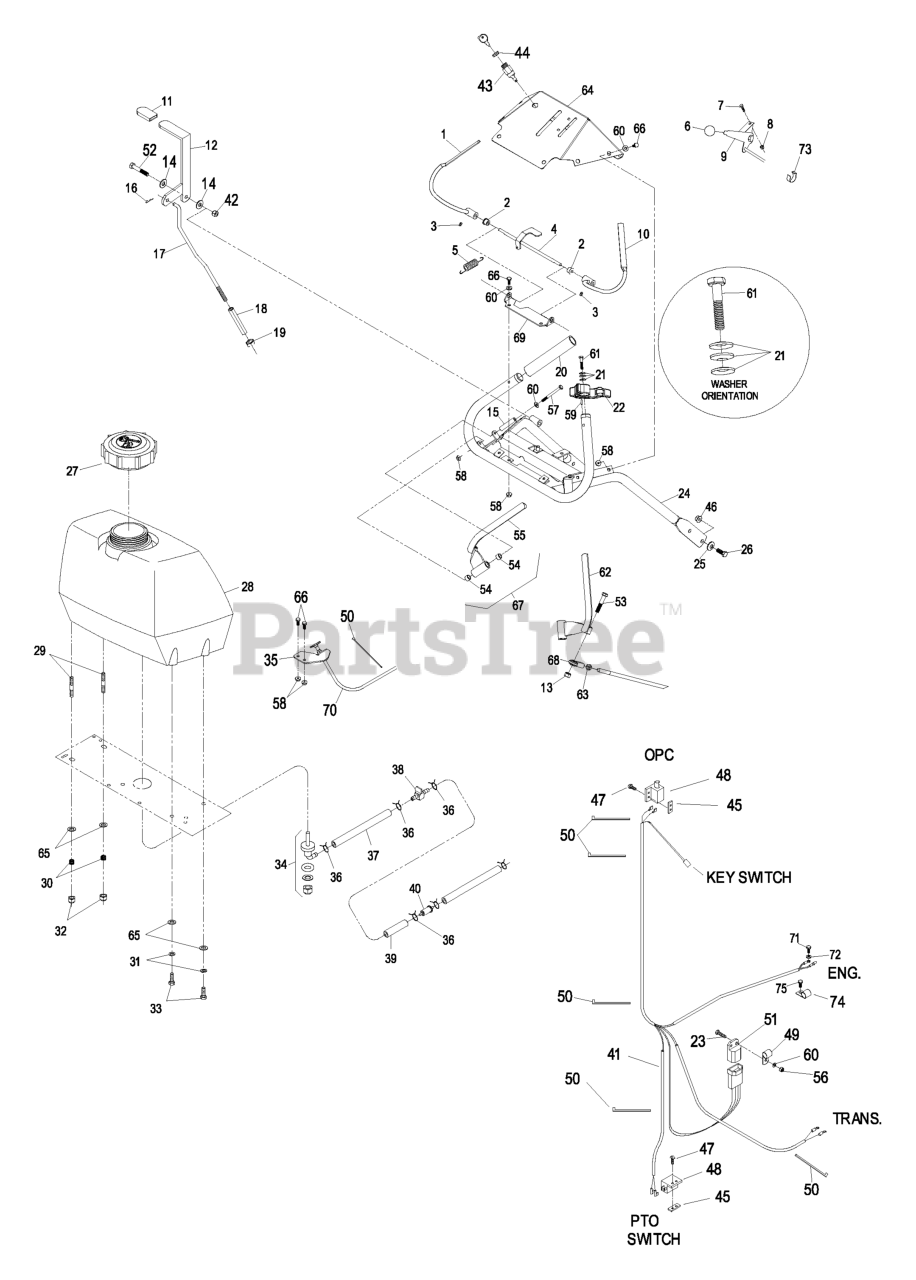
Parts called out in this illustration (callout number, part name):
2	BUSHING-NYLON
3	SCREW-SET
4	WLD,OPC LEVER AXLE
5	SPRING-EXTENSION
6	KNOB-BALL
7	BOLT-CARR
8	NUT-LOCK, NI
9	THROTTLE CABLE ASM
11	GRIP-LEVER
13	Nut, Nyloc 5/16-18
14	WASHER-FLAT
15	BUSHING-LEVER, DRIVE
16	PIN-COTTER
17	LINK,BLADE ENGAGE (PLTD)
18	TURNBUCKLE
19	NUT-HEX
20	GRIP-BAR, HANDLE
21	WASHER-SPRING
23	Nut, Nyloc 1/4
24	WLD,UPPER ECS HANDLE
25	WASHER-BELLEVILLE
26	SCREW-HH
28	ASM,FUEL TANK W/B
29	STUD
30	SPRING-TANK, FUEL
31	WASHER-LOCK
32	NUT-LOCK, NI
33	SCREW-HH
34	FITTING-FUEL, BULKHEAD
35	BRACKET-CABLE, CHOKE
37	HOSE-FUEL
38	VALVE-FUEL
39	HOSE-FUEL
40	Pn 41019-1055 W/6" Fuel Line
42	NUT-LOCK, NI
43	SWITCH & KEY (INCLUDES NU
44	NUT-SWITCH, IGNITION
45	PLATE-TAPPED
46	NUT-HHF, WHIZ
47	SCREW-PPH
48	SWITCH-OPEN, NORMALLY
49	CLIP-LOOM
50	TIE-CABLE
51	MODULE-INTERLOCK
52	SCREW-HH
53	SCREW-HH
54	BUSHING-SLEEVE
56	SCREW-HH
57	SCREW-HH
60	WASHER-FLAT
61	SCREW-HH
63	NUT-HJ
64	ASM,CONSOLE W/DECALS
65	WASHER-PLAIN
66	SCREW-HH
67	DRIVE LEVER-ASM, RH
68	JOINT-BALL, END
69	BRACKET,OPC AXLE
70	CABLE-CHOKE
71	SCREW-HH
72	WASHER-LOCK
73	CLIP-CABLE
74	CLIP-LOOM
75	SCREW-HH
